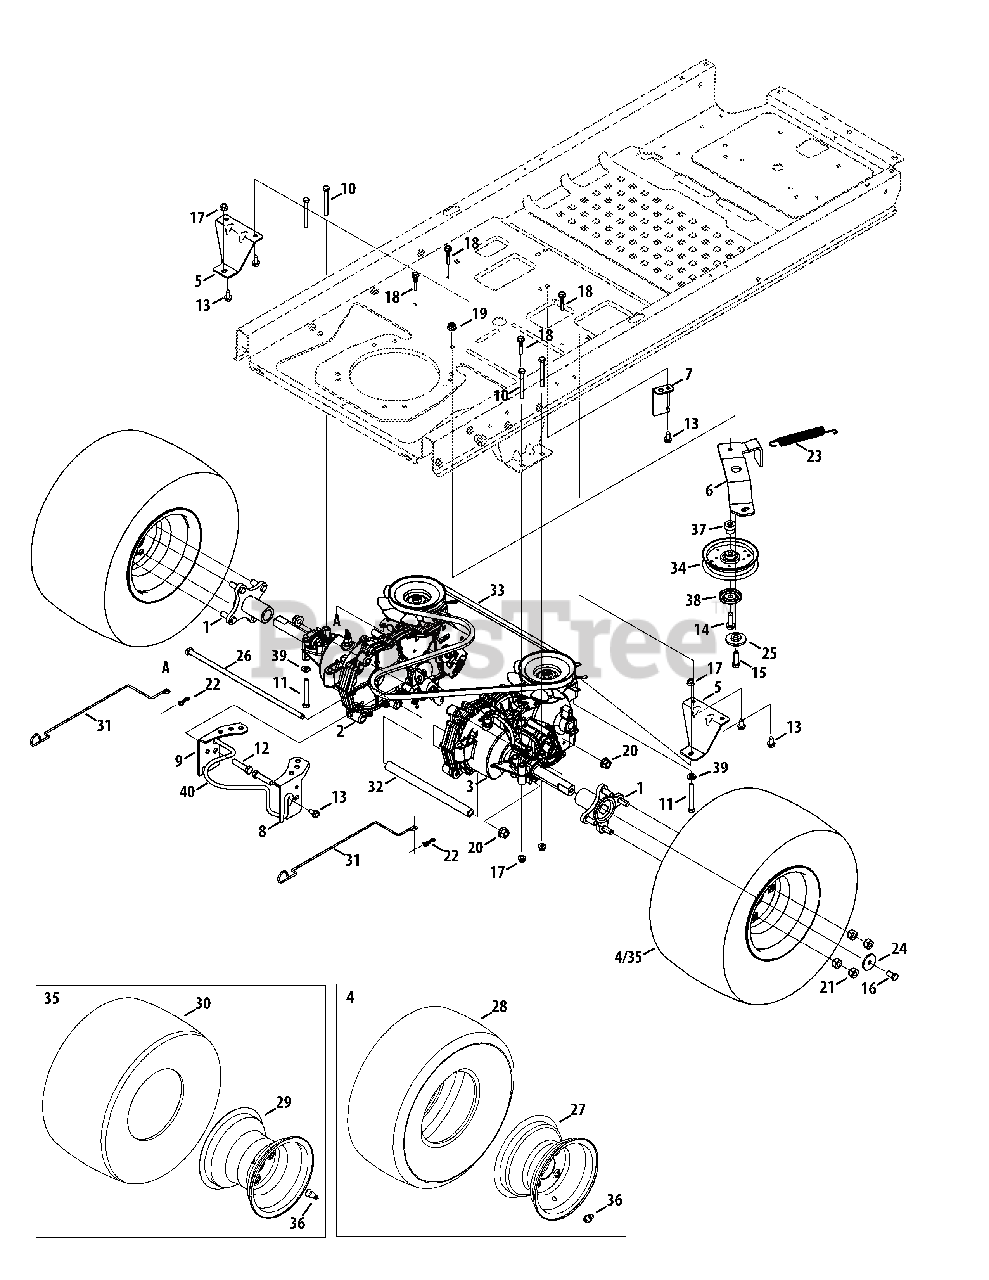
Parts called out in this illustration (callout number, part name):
1	Wheel Hub Assembly
2	Transmission Assembly, LH
3	Transmission Assembly, RH
4	Complete Wheel, 18 x 8.5-8 (42" & 46")
5	Transmission Mounting Bracket
6	Idler Bracket
7	Spring Mounting Bracket
8	Transmission Bracket
9	Transmission Bracket
10	Hex Screw, 5/16-18 x 2.75
11	Hex Screw, 5/16-18 x 2.25
12	Hex Screw, 7/16-20 x 1.75
13	Hex Washer Screw, 5/16-18 x .750
14	Hex Washer Screw, 3/8-16 x 1.250
15	Hex Screw, 3/8-16 x 1.00
16	Hex Screw, 3/8-16 x .75
17	Flange Lock Nut, 5/16-18
18	Keeper Rod, .25 x 1.535
19	Jam Lock Nut, 3/8-16
20	Flange Lock Nut, 7/16-20
21	Lug Nut, 7/16-14
22	Bow-Tie Cotter Pin
23	Extension Spring, .75 Dia. x 6.02
24	Flat Washer, .390 x 1.50 x .134
25	Shoulder Spacer, .884 x .190
26	Rod, .405 Dia. x 14.0 LG
27	Rim Only, (42" & 46")
28	Tire Only, 18 x 8.5-8 (42" & 46")
29	Rim Only, (54")
30	Tire Only, 18 x 9.5-8 (54")
31	Bypass Rod
32	Tube, .51 ID x .75 OD x 10.2
33	Belt, A-Type x 67.0
34	Idler Pulley, 4.25 Dia.
35	Complete Wheel, 18 x 9.5-8 (54")
36	Valve Tubeless
37	Shoulder Spacer
38	Pulley Cap
39	Flat Washer, .330 x .630 x .064
40	Engine Keeper Rod (42")
